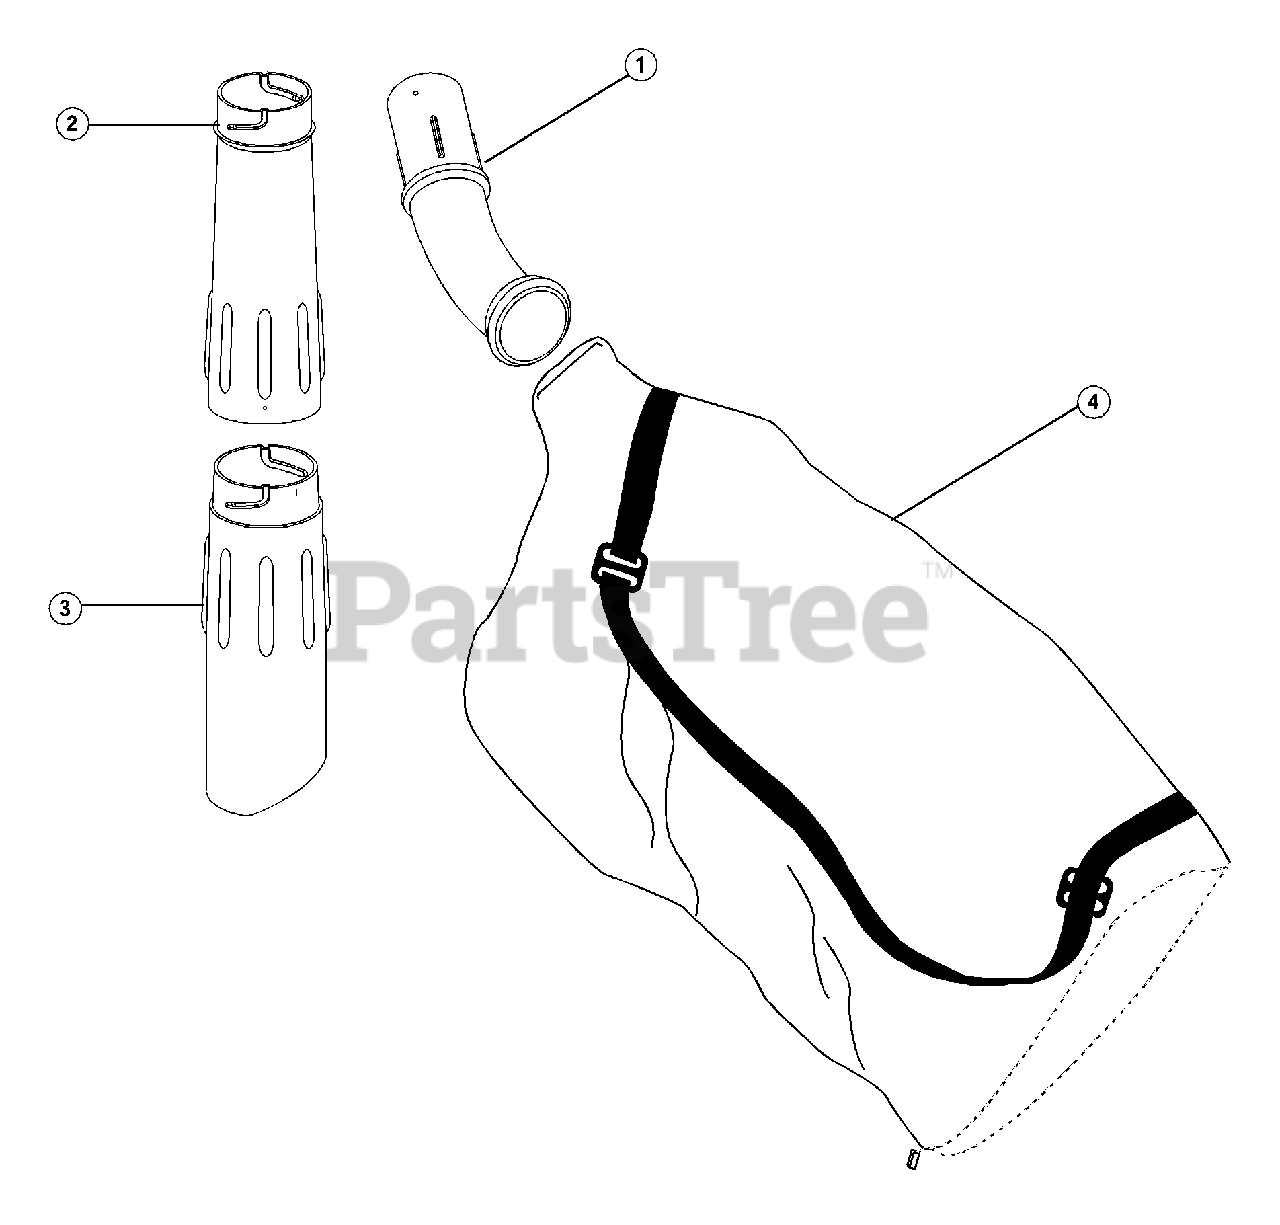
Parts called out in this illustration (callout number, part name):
2	Upper Vacuum Tube
3	Lower Vacuum Tube
4	Bag
